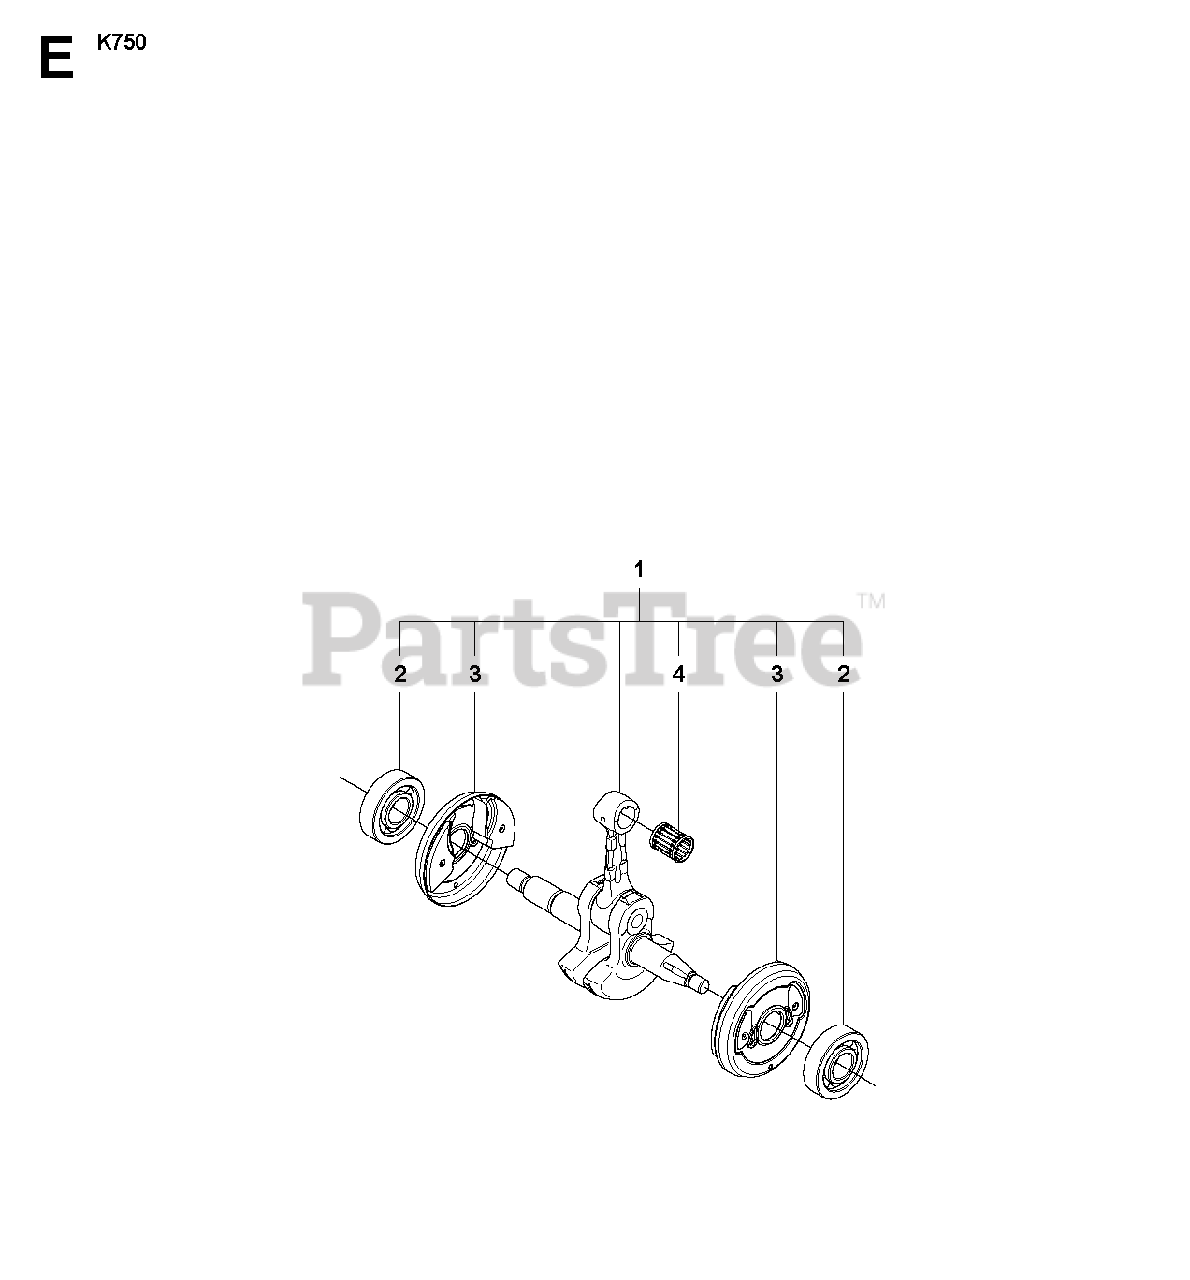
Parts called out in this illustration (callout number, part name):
1	CRANKSHAFT ASSYIncl. 2 - 4
2	BALL BEARING
4	NEEDLE BEARING
